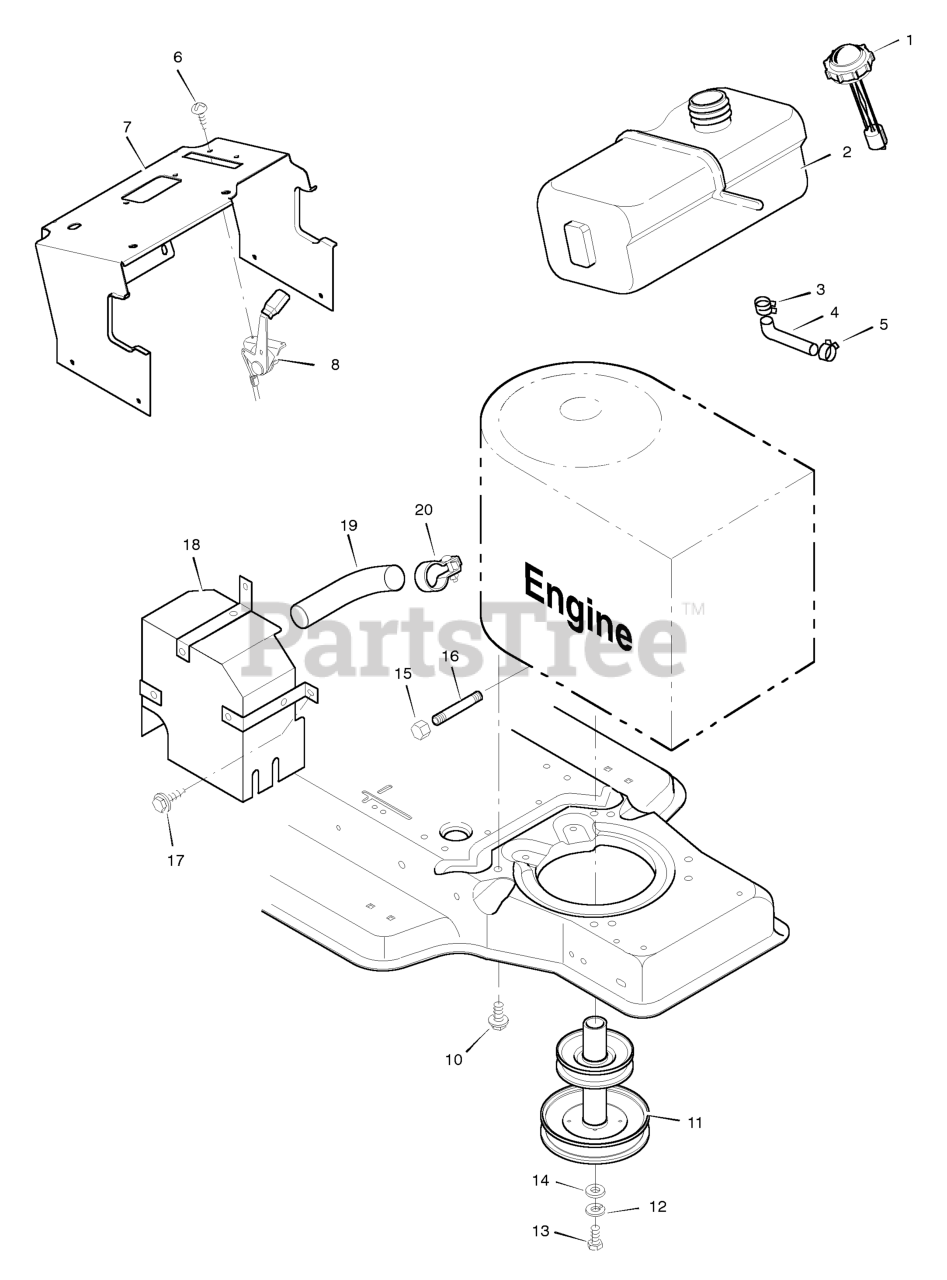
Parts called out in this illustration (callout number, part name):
1	Fuel Cap
2	Fuel Tank
3	Hose Clamp
4	Fuel Line
5	Hose Clamp
7	Support, Dash
8	Throttle Control
9	Engine *
10	Bolt, Engine Mount
11	Stack Pulley Assembly
12	Lockwasher
13	Bolt, Hex
15	Cap, Oil Drain
16	Pipe, Oil Drain
18	Shield, Heat
19	Pipe, Exhaust
